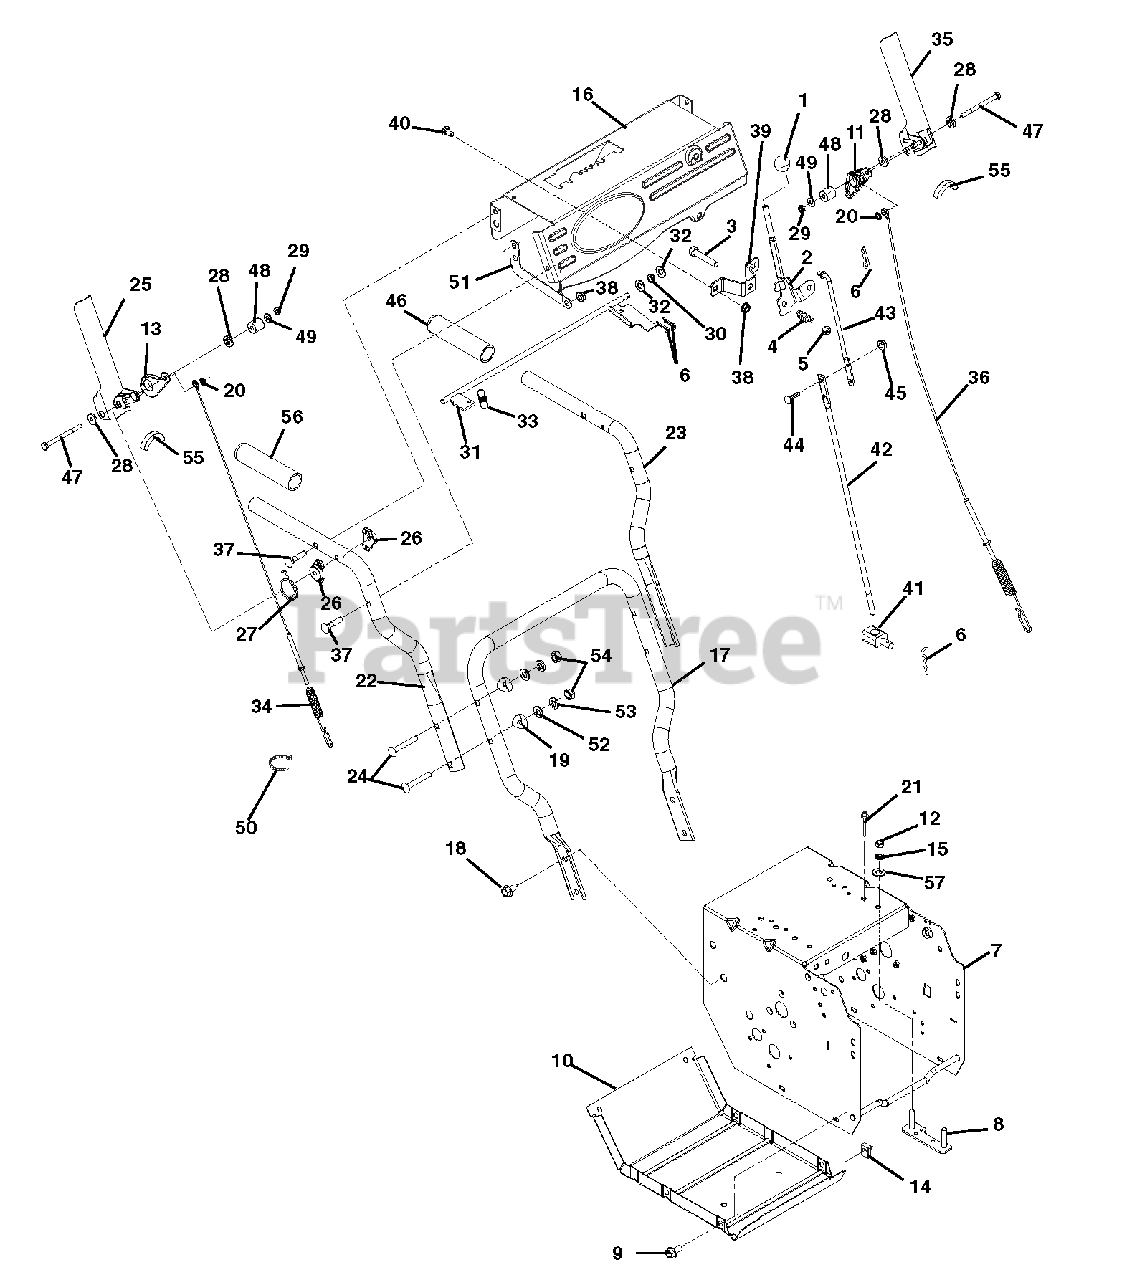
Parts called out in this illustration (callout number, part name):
1	KNOB,BALL -BLACK 1.47" .375-16
2	WMT, SHIFT LEVER
3	@BLT-HEX .38-16X2.00 GR5 YWZC
4	SG-COMP .125X.781X1.250
5	@NUT-LK-TOP-FLG .38-16 YWZC
6	PIN-HAIR INT .08X.18X1.18 YWZC
7	FRAME, 920/921
8	STRAP, ENGINE BOLT-WELDMENT
9	BLT-HEX .25-20X.75 HWH YZ GR5
10	COVER, BOTTOM
11	CAM, INTERLOCK - LH
12	@NUT-HEX .31-18 YWZC
13	CAM, INTERLOCK - RH
14	NUT-RTNR .25-20X.56
15	WSHR-LK .312X.097 HVY YWZC
16	CONTROL PANEL W/DECAL
17	HANDLEBAR, LOWER - DELUXE
18	BLT-SERHFWH .38-16X.75 YWZC
19	SPACER, HANDLEBAR
20	RG-RTNG-EXT .250X.010
21	RVT-POP .187 YZ
22	HANDLEBAR, UPPER - RH COMP/DEL
22	HANDLEBAR, UPPER-RH 920 BRUSH
23	HANDLEBAR, UPPER - LH COMP/DEL
24	@BLT-RDHDSQNK .31-18X2.25 G5YZ
25	PADDLE, CLUTCH - RH COMPACT
26	SPACER, HANDLEBAR
27	SPRING, TORSION
28	BSHG, FLG .266X.42X.150 PM
29	NUT-JAM-NYL .250-20 W/INSERTYZ
30	BUSHING, POLYLINER-.38 SNAPIN
31	WELDMENT, INTERLOCK SHAFT
32	@WSHR-FL-STL.406X.812X.065 YWZ
33	SPRING, EXTENSION
34	CABLE, ATTACHMENT
35	PADDLE, CLUTCH - LH COMPACT
36	CABLE, TRACTION - DELUXE
37	BLT-RDHDXLSQNK .31-18X1.5 G5YZ
38	@NUT-LK-TOP-FLG .31-18 YWZC
39	BRKT, SHIFT MOUNT
40	@BLT-RHDSSQNK .31-18X.62 G5YZ
41	PIVOT,SHIFT ROD .375-16(TRUNN)
42	ROD, SHIFT - LOWER
43	ROD, SHIFT - UPPER
44	@BLT-RDHDSQNK .25-20X.75 G5YZ
45	@NUT-LK-TOP-FLG .25-20 YWZC
46	HANDLE GRIP
47	@BLT-HEX .25-20X3.25 YWZC
48	BSHG, SLV .266 X .750 X .750
49	@WSHR-FL-STL.281X.62X.065 YWZC
50	CABLE TIE LG 5-1/2
51	STRAP, SUPPORT - DASH PANEL
52	@WSHR-FL-STL.38X.875X.083 YWZC
53	WSHR-LK .312X.097 HVY YWZC
54	@NUT-LK-NYL .312-18 YWZC
55	EDGING, CLUTCH PADDLE - 2.00"
56	HANDLE GRIP - SHORT
56	HANDLE GRIP
57	@WSHR-FL-STL.344X.688X.065YWZC
